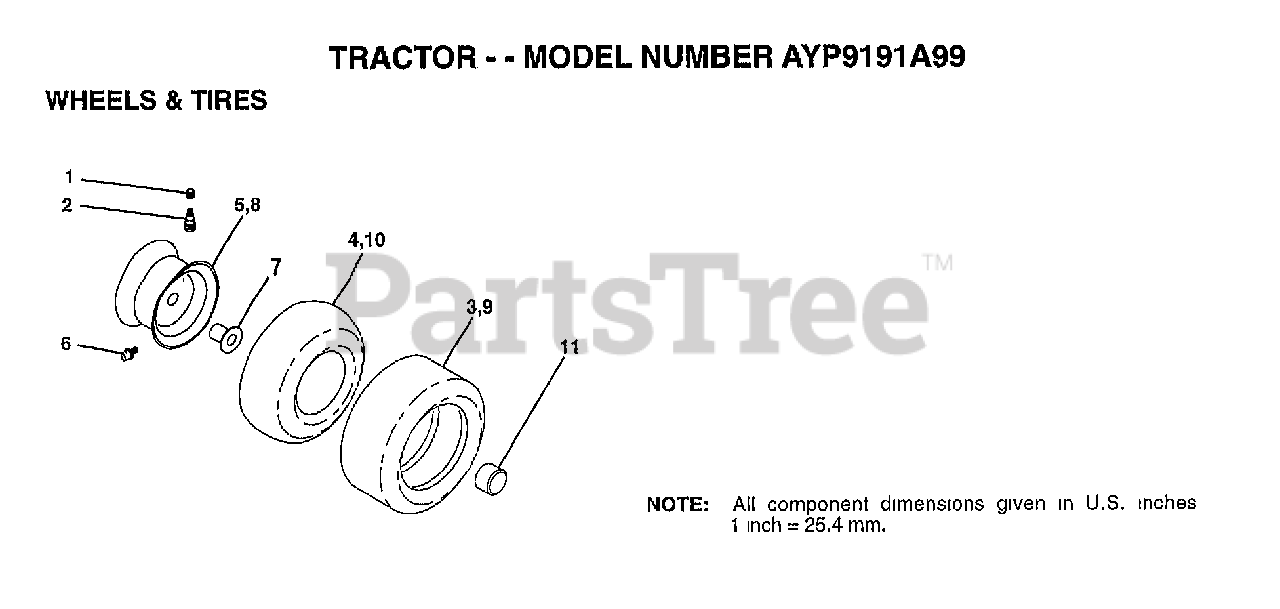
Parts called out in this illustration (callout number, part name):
1	VALVE CAP
2	VALVE STEM LT
4	TUBE.5.3/4.5/6
5	"RIM ASM 6"" FRT"
6	FITTING LT
7	"FLANGE, BEARING"
8	"RIM AS 8"" REAR"
9	TIRE.20X8-8
10	TUBE.18X9.5-8
11	HUB CAP
